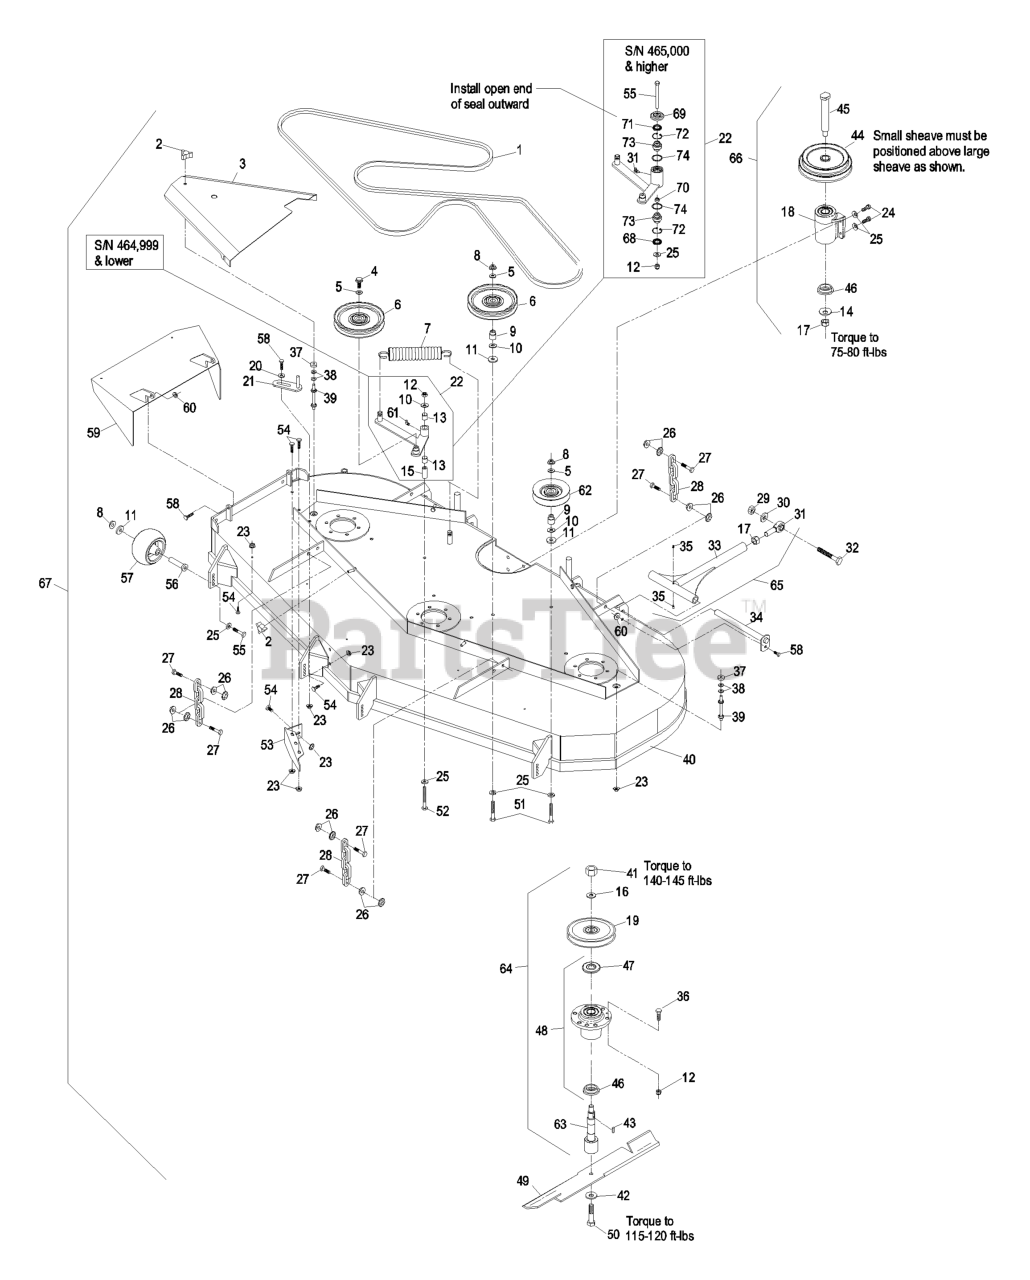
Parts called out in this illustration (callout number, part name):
1	BELT-V
2	KNOB-3 PRONG
3	SHIELD,BELT RH
4	SCREW-HHF
5	WASHER-FLAT
8	NUT-HHF, WHIZ
9	BUSHING-IDLER
10	WASHER-FLAT
12	NUT-LOCK, NI
13	SLEEVE-BEARING
14	WASHER-SPRING
15	BUSHING
17	NUT-HEX
19	SHEAVE,BLADE DRIVE 7.5
20	WASHER-SPRING
21	GUIDE-BELT
22	KIT,DECK IDLER LZ/XP
24	SCREW-HH
25	WASHER-BELLEVILLE
27	SCREW-HH
28	CHAIN-LIFT, DECK
29	NUT-HEX
30	WASHER-LOCK
31	BALLJOINT-SPHERICAL
32	SCREW-HH
34	PIN-STRUT
35	FITTING-GREASE
36	SCREW-HH
38	WASHER-FLAT
39	STUD-SHIELD, BELT (SHORT)
40	ASM,DECK W/DECALS LZ/XP72
42	WASHER-BLADE BOLT, HEAVY
44	SHEAVE, JACKSHAFT DOUBLE
45	JACKSHAFT
46	SPACER-GUARD, BOTTOM
47	GUARD-BEARING, TOP
50	SCREW-CAP
51	SCREW-HH
52	SCREW-HH
53	WLD,BAFFLE DISCHARGE
54	SCREW-HH
55	SCREW-HH
56	BUSHING-ROLLER
57	ROLLER-SCALP, ANTI
58	SCREW-HH
59	WLD,CHUTE 72
60	NUT-LOCK, NI
61	FITTING-GREASE, 90 DEG
62	PULLEY-IDLER
63	SPINDLE,SHORT
65	ASM,STRUT 72 LONG
66	KIT,JACKSHAFT 60/72-3750
67	Complete Deck Asm
68	SEAL-LIP, DOUBLE
69	GUARD-TOP
70	SPACER
71	SEAL-LIP, SINGLE
72	RING-SNAP
73	BEARING-SPHERICAL
74	O-RING
